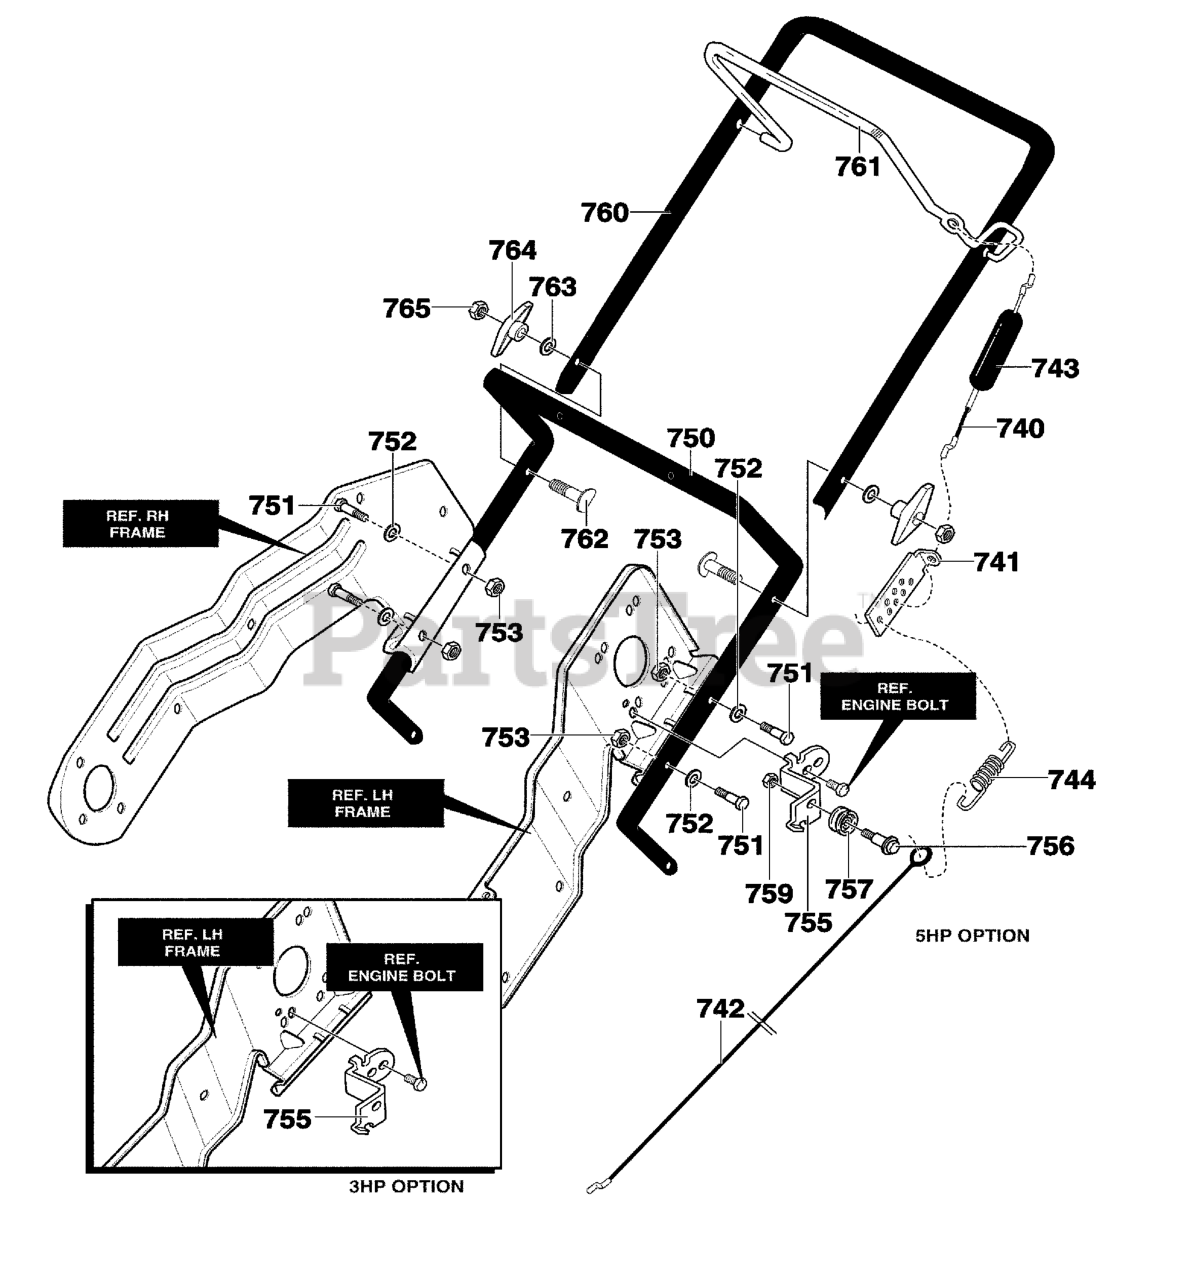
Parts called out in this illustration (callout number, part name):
740	CABLE, UPPER
741	BRACKET, CABLE ADJ
742	CABLE, LOWER CONTROL
743	BOOT, CLUTCH SPRING
744	SPRING, EXTENSION
750	HANDLE, LOWER
751	SCREW, 1/4-20X1.25
752	WASHER, FLAT
753	NUT, 1/4-20
755	BRACKET, CABLE
757	PULLEY, NYLON
759	NUT, 1/4-20
760	UPPER HANDLE
761	BAIL, CONTROL
762	BOLT, 5/16-18X2.00
763	WASHER, FORM
764	T-KNOB
765	NUT, 5/16-18
